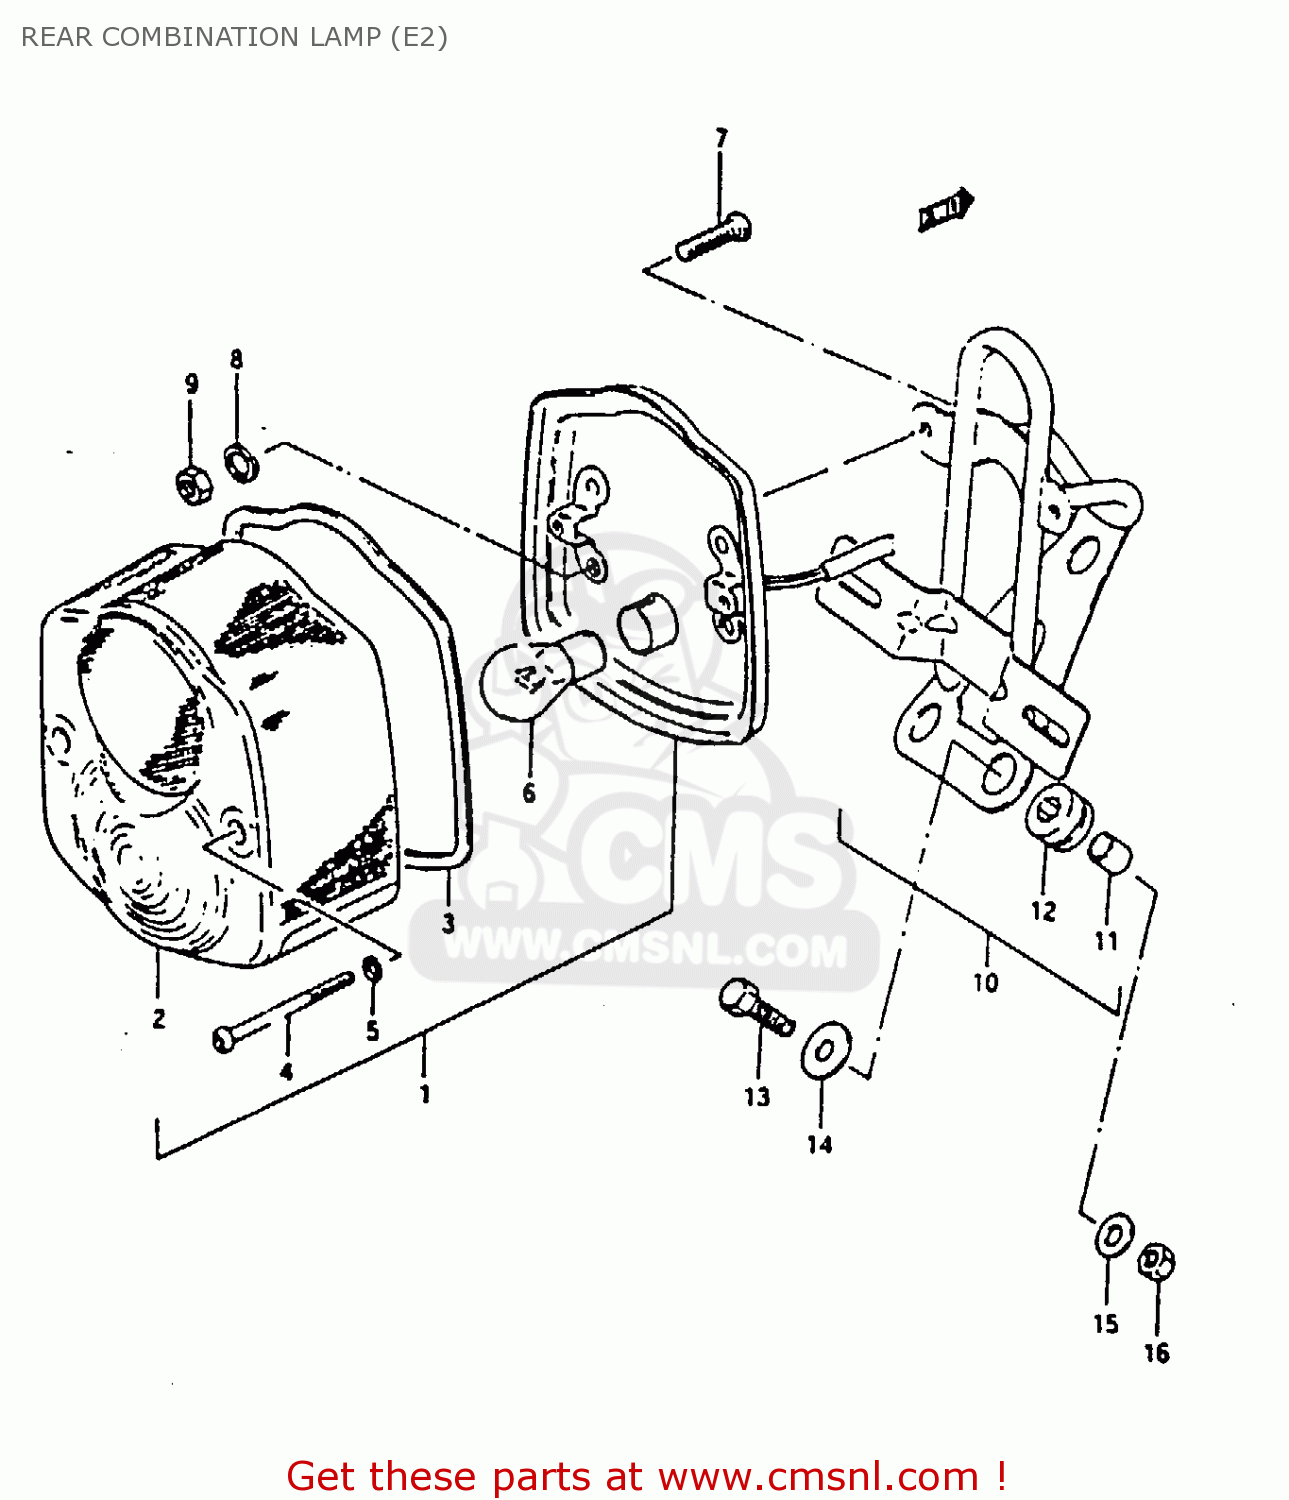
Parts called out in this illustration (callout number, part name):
1	LAMP UNIT, TAIL
2	LENS
3	GASKET (NAS)
4	SCREW
5	GASKET (NAS)
6	BULB (6V,21/5W)
7	SCREW
8	LOCK WASHER
9	NUT
10	BRACKET ASSY
11	SPACER,RR COMBINATION
12	CUSHION,RR COMBINATION
13	BOLT
14	WASHER (6.5X20X1.2)
15	WASHER
16	NUT 6MM
